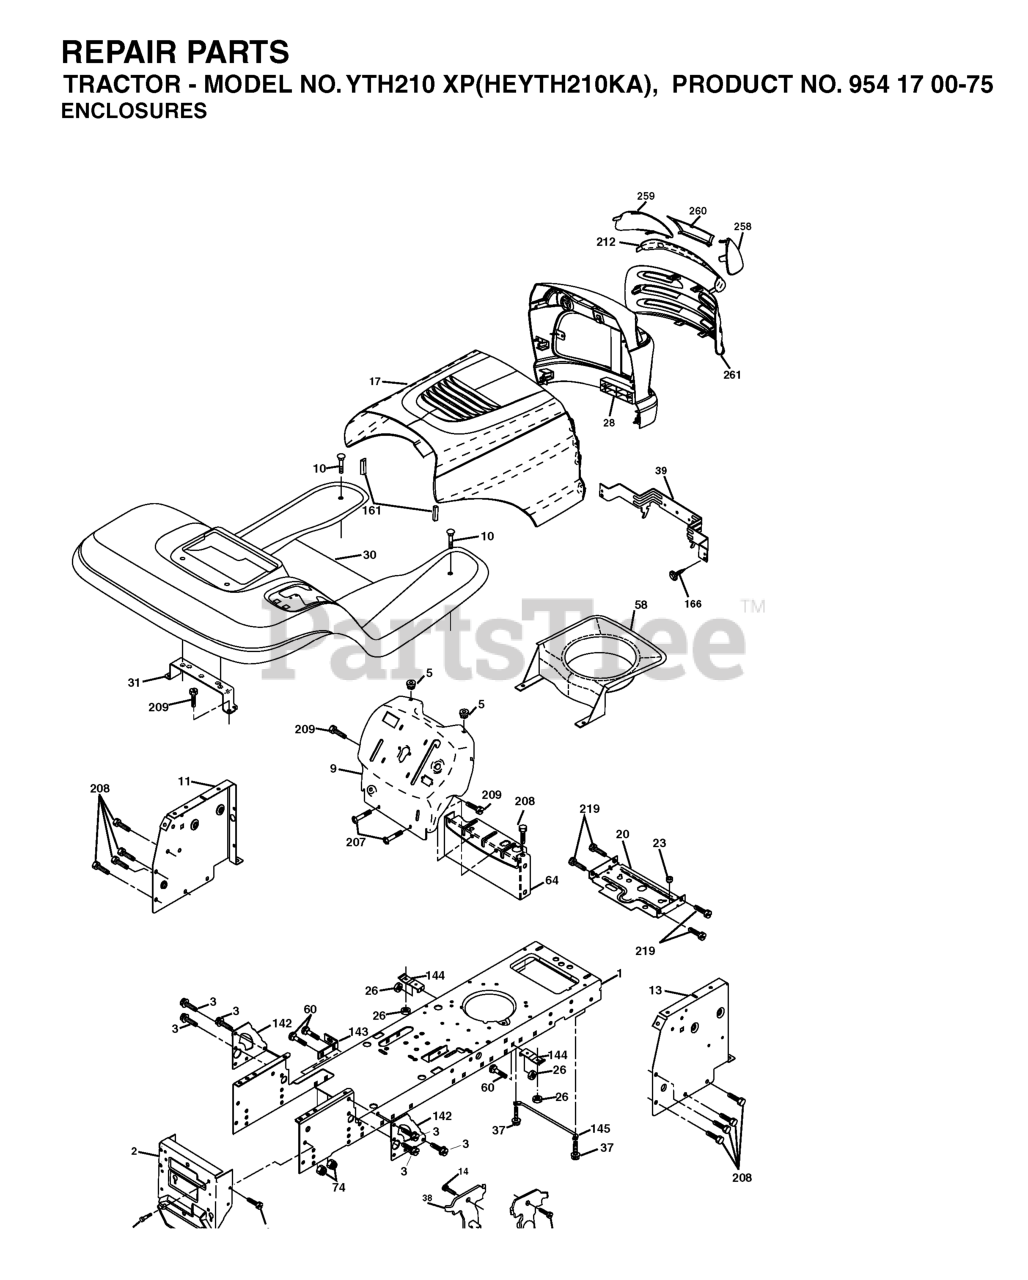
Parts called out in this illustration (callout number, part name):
1	CHASSIS STAMPING
2	DRAWBAR, 12GA
3	SCREW 3/8-16X3/4
5	BUMPER.RUBBER.HOOD
9	DASH(SUBS)
10	BOLT D
11	PANEL.DASH.LH.LTX
13	PANEL ASM, DASH RH
17	HOOD
20	PLATE MTG.BATTERY/FUEL TANK
23	BUSHING.SNAP.NYL.BLK.
26	NUT
30	FENDER FOOTREST
31	BRACKET.SUPPORT.FENDER
37	Screw 5/16-18 x 1/2 Hex, Self Tapping 5/16-18 x 1/2
38	BRACKET.ASM.PIVOT.MOWER.REAR
39	BRACKET PIVOT LASER
58	DUCT, INTAKE AIR
60	Bolt - Rd. Hd. Sq. Neckiage 3/8 16 x 3/4
64	DASH LOWER
142	PLATE REINFORCEMENT
143	BRACKET, SWAY BAR
144	BRKT, FOOT REST
145	ROD PIVOT CHASSIS/HOOD
161	BUMPER.HOOD.LARGE.1.75"
166	SCREW
206	SHOULDER BOLT 5/16-18TT
207	SCREW, 5/16-18 X 1/2
208	SCREW 3/8-16X1/2
212	INSERT.LENS.REFLECTIVE
219	SCREW
258	LENS LH
259	LENS LH
260	COVER.LENS.HUSQ.LASER
